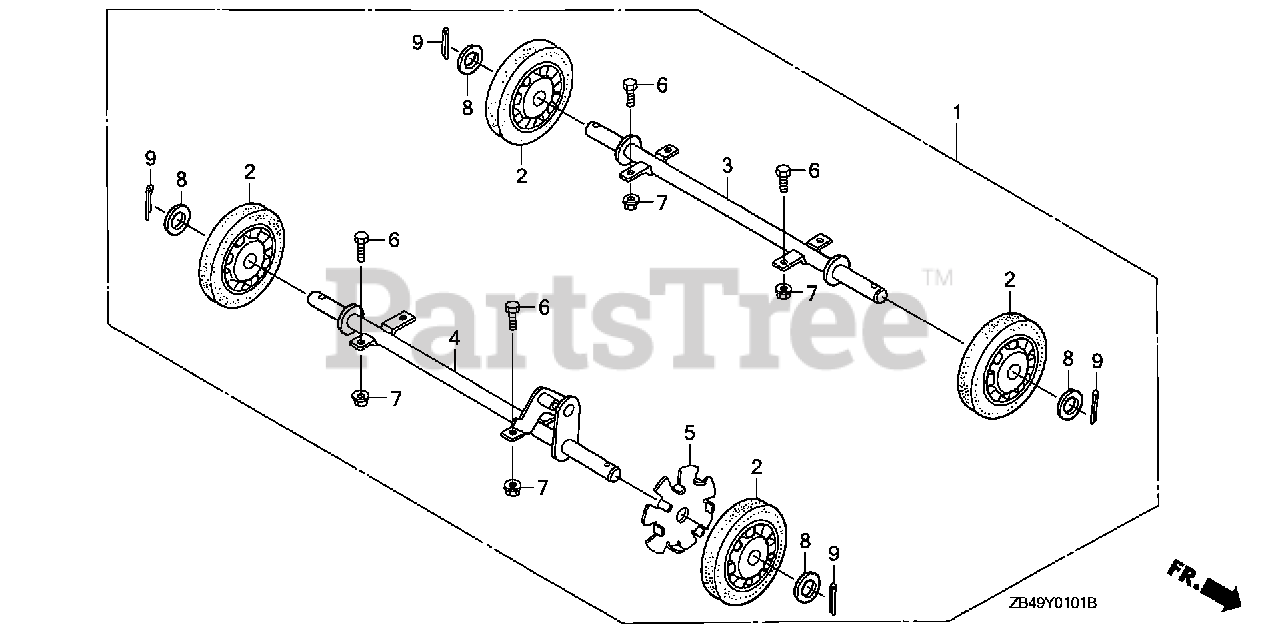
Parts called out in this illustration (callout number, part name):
1	WHEEL KIT (4-WHEELS)
2	WHEEL
3	SHAFT, R. WHEEL
4	SHAFT, L. WHEEL
5	PLATE, LOCK
6	BOLT, HEX. (8X16)
7	NUT, FLANGE (8MM)
8	WASHER, PLAIN (20MM)
9	PIN, SPLIT (4.0X28)
9	PIN, SPLIT (4.0X30)
